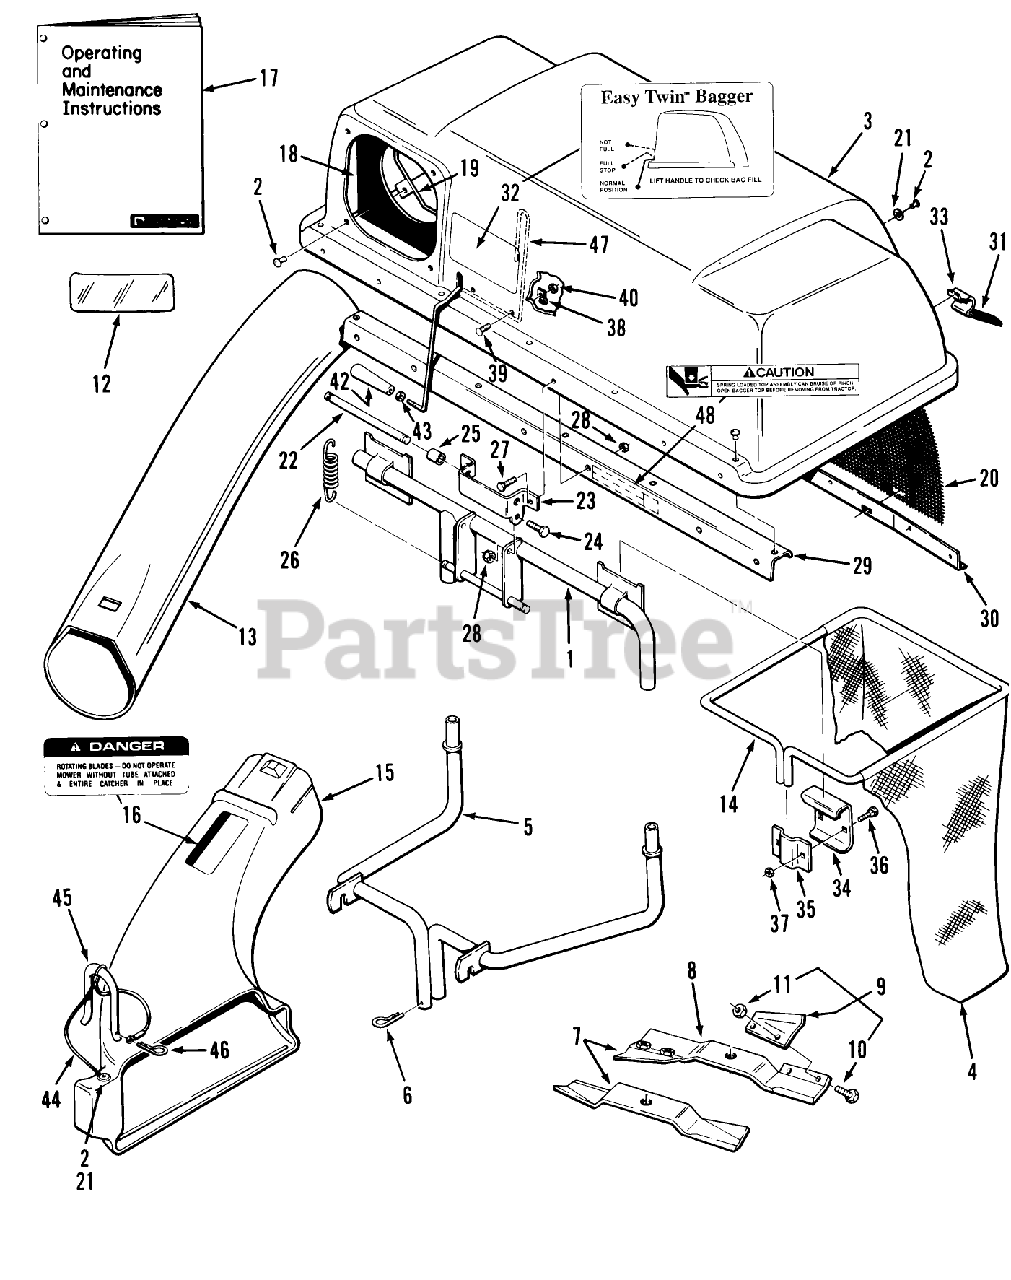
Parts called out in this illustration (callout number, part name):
2	RIVET-BLIND
5	ASM-QUICK ATTACH *B
6	Hairpin
7	KIT-BLADE (SERVICE)
8	ASS'Y-HI LIFT BLADE
9	S/A 37 LIFT TAB KIT
10	BOLT 5/16-18X5/8
11	NUT-HEX
12	DECAL-OVERLAY
13	CHUTE-BAGGER (L)
16	DECAL-DANGER
17	Operating and Maintenance Instructions
19	CLAMP-SEAL
20	SCREEN-BAGGER
22	PIN-SPRING
26	SPRING-EXTENSION
42	HANDLE-TAPERED
44	LANYARD-ELBOW LATCH
45	LATCH-ELBOW
46	Hairpin Cotter
47	FEELER-FILL, BAG
